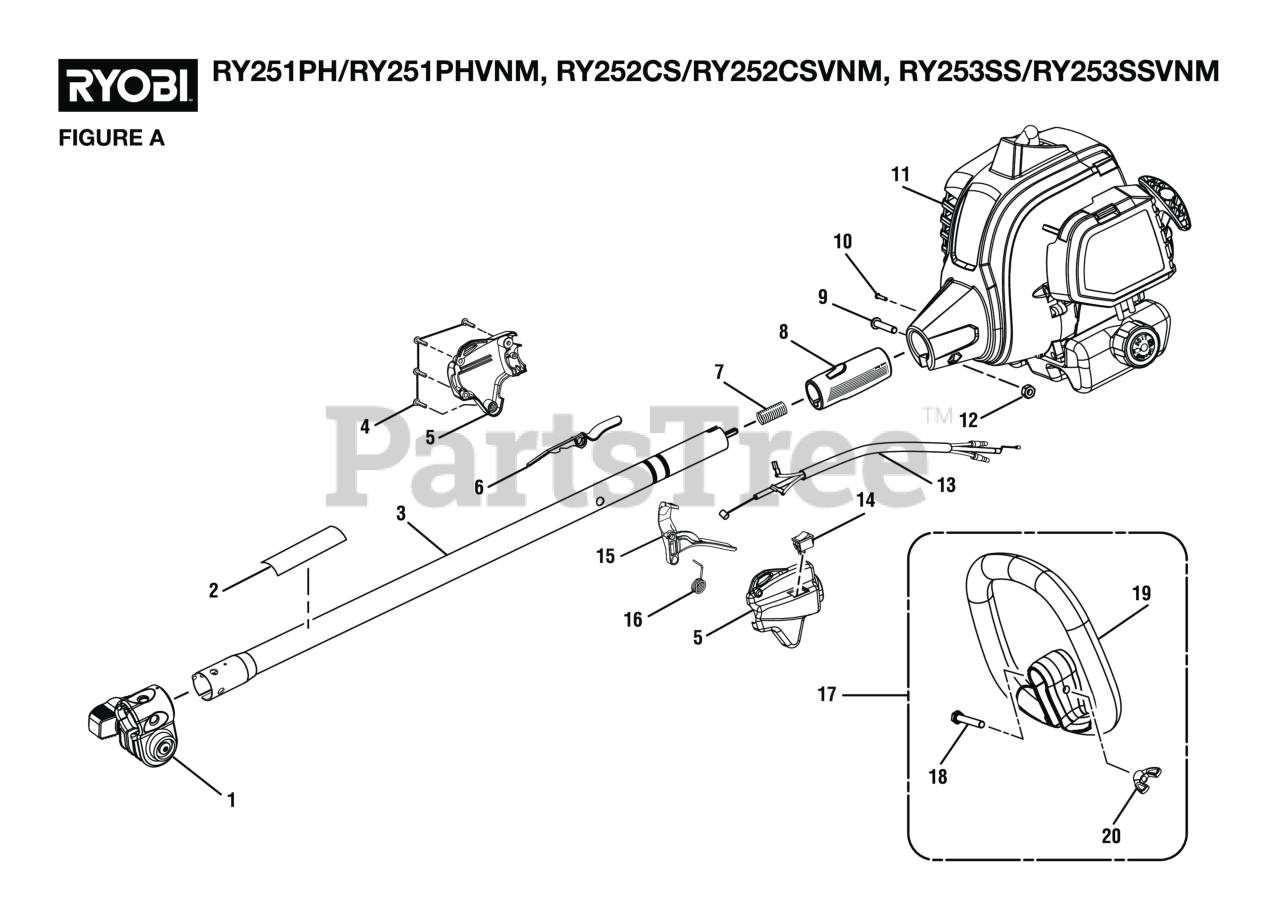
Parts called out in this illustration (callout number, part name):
1	Boom Clamp Assembly
2	Warning Icon Label
3	Upper Boom Assembly (Inc. Key Nos. 1-2)
4	Screw (M4 x 20 mm, T20 Torx Pan Hd. S.T.)
5	Control Handle Assembly (Inc. Key No. 6)
6	Trigger Lock
7	COMPRESSION SPRING
8	Rear Handle Grip
9	Screw (M6 x 30 mm, T27 Torx Button Hd.)
10	Screw (M4 x 8 mm, T25 Torx Pan Hd. T.F.)
11	Powerhead Assembly w/Labels
12	Hex Nut (M6.3 x 1)
13	Throttle Cable and Wire Assembly
14	Stop Switch (Momentary Contact)
16	Torsion Spring (Throttle Trigger)
17	Auxiliary Handle Assembly
18	Screw (1/4-20 x 40 mm, Cap Hex Hd.)
19	Front Handle
20	Wing Nut (1/4-20, Plastic)
